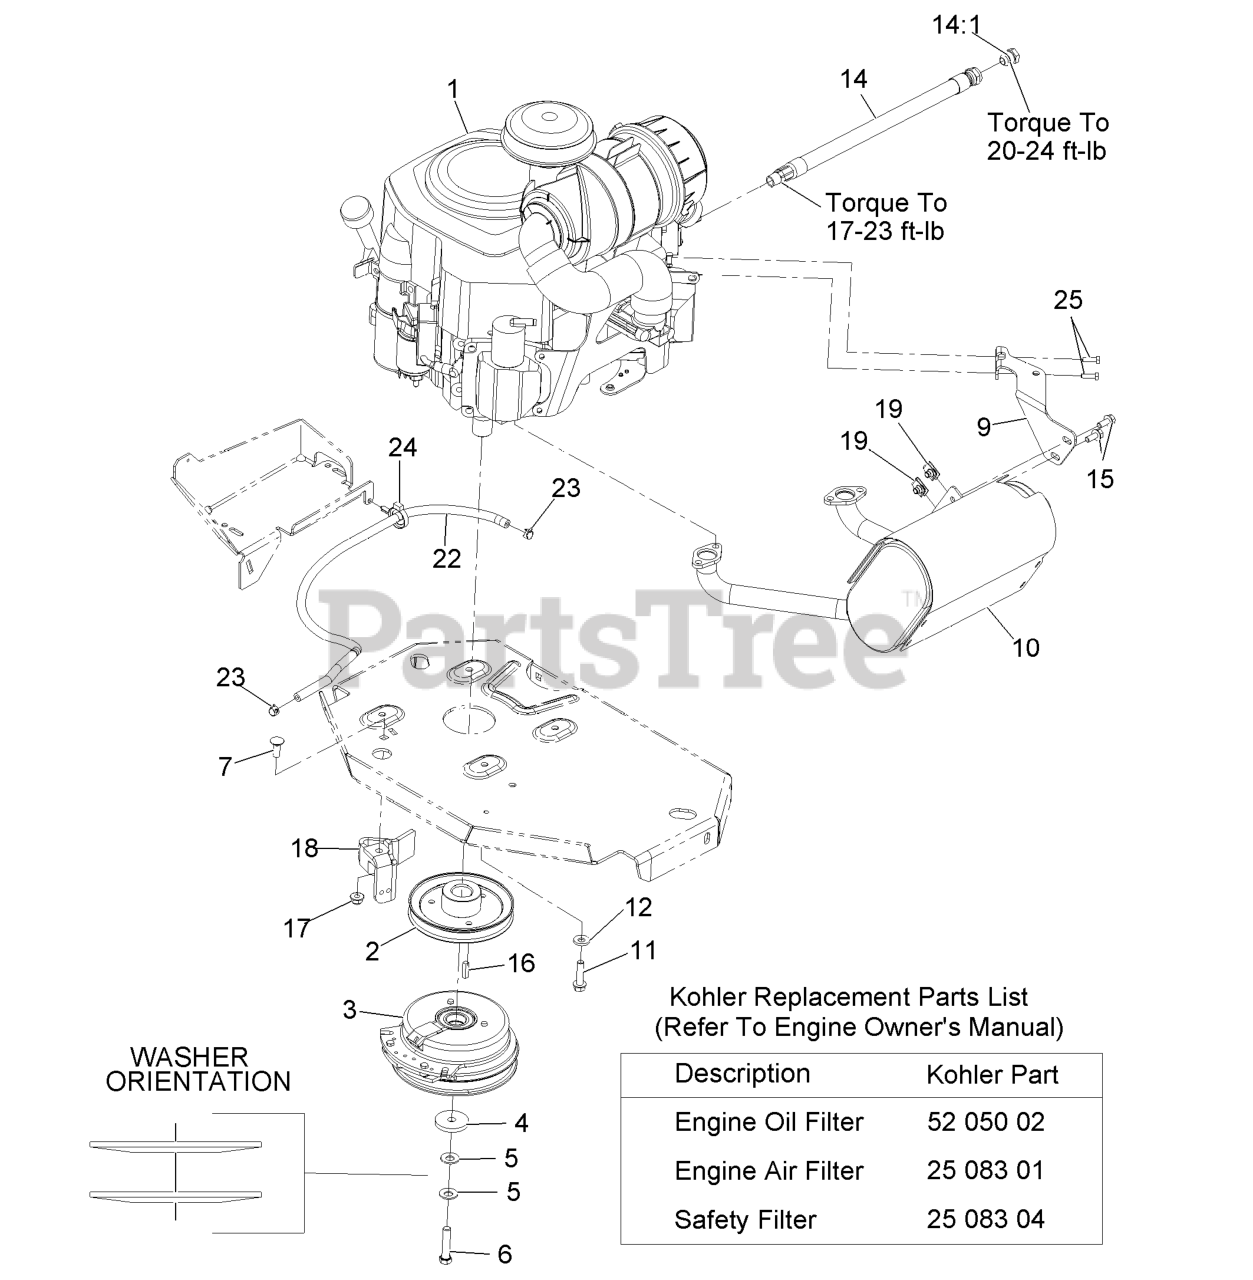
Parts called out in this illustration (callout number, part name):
1	Engine,Koh 23hp Hd
2	SHEAVE
3	CLUTCH KIT
4	WASHER-CLUTCH
5	WASHER-SPRING
6	SCREW-HH W/LOCTITE
7	SCREW-CARR
9	MUFFLER BRACKET KIT
11	SCREW-HWH
12	WASHER-BELLEVILLE
15	SCREW-HHF
17	NUT-HF, NI
18	CLUTCH-ANCHOR
22	HOSE-FUEL
23	CLAMP-HOSE
24	CLAMP-HOSE
25	SCREW-HH M6-1 X 20Mm W/Patch
